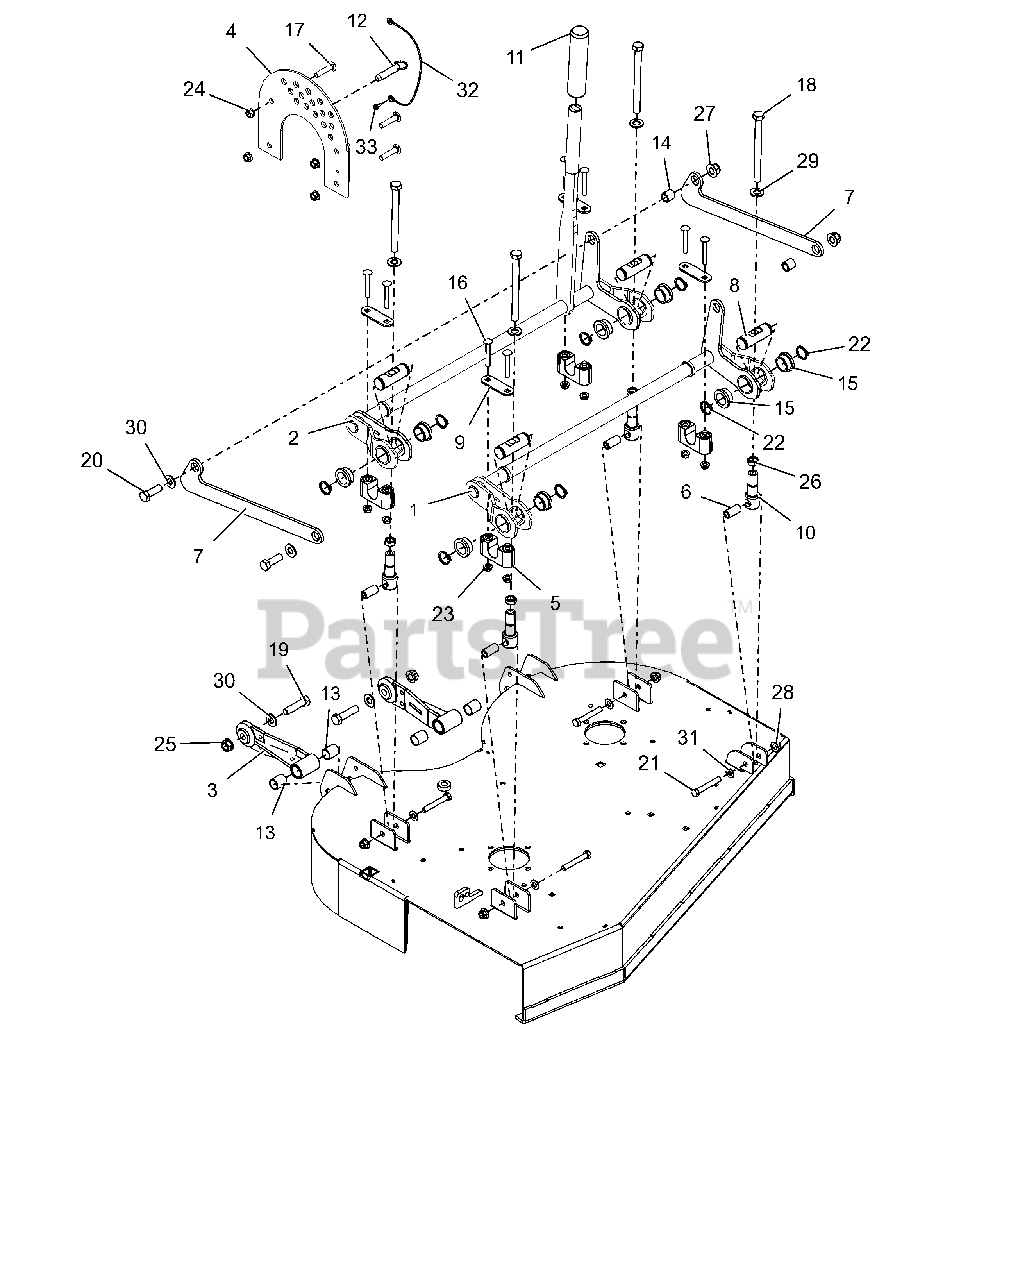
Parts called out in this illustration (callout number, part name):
1	WLDMT, DECK LIFT
2	WLDMT, DECK LIFT
3	WLDMT, PUSHER LINK BAR
4	WLDMT, DECK INDEXING (RED)
5	ASM-BUSHING, DECK LIFT
6	SPACER, DECK LEVELING
7	LINK, DECK LIFT
8	PIN, DECK LIFT
9	PLATE, BEARING SUPPORT
10	LINK, DECK LIFT FORMED
11	GRIP, DECK LIFT
12	PIN, .500 x 2.000 USABLE LG BALL
13	BRG, .750 X .875 X 1.000
14	BSHG, SLV .510 X .751 X .750
15	BSHG,FLG 1.0 X 1.25 X 1.5 X .6
16	BLT-RDHDSQSHNK .31-18X2.25 YWZ
17	BLT-RHDSSQNK .38-16X1.75 G5YZ
18	BOLT,.50-13X6.00-2.50 LG THD
19	BLT-HEX .500-13X2.00 GR8 YWZC
20	@BLT-HEX .50-13X1.50 GR5 YWZC
21	@BLT-HEX .38-16X2.50 GR5 YWZC
22	RG-RTNG-EXT 1.00X.078
23	@NUT-LK-CTR-FLG .31-18 YZ GR F
24	NUT-LK-CTR-FLG .38-16 YWZC
25	NUT-LK-CTR-FLG .50-13 YWZC
26	NUT-JAM .50-13 YWZC
27	@NUT-LK-NYL-FLG .50-13 YWZC
28	@NUT-LK-NYL-FLG .38-16 YWZC
29	FLATWASHER 1/2 SAE HARD 15906
30	@WSHR-FL-STL.531X1.06X.095YWZC
31	@WSHR-FL-STL.406X.812X.065 YWZ
32	CABLE, 12.0 LANYARD, NYLON
33	@SCR-TAP 10-24X.50 HWH TR YWZC
